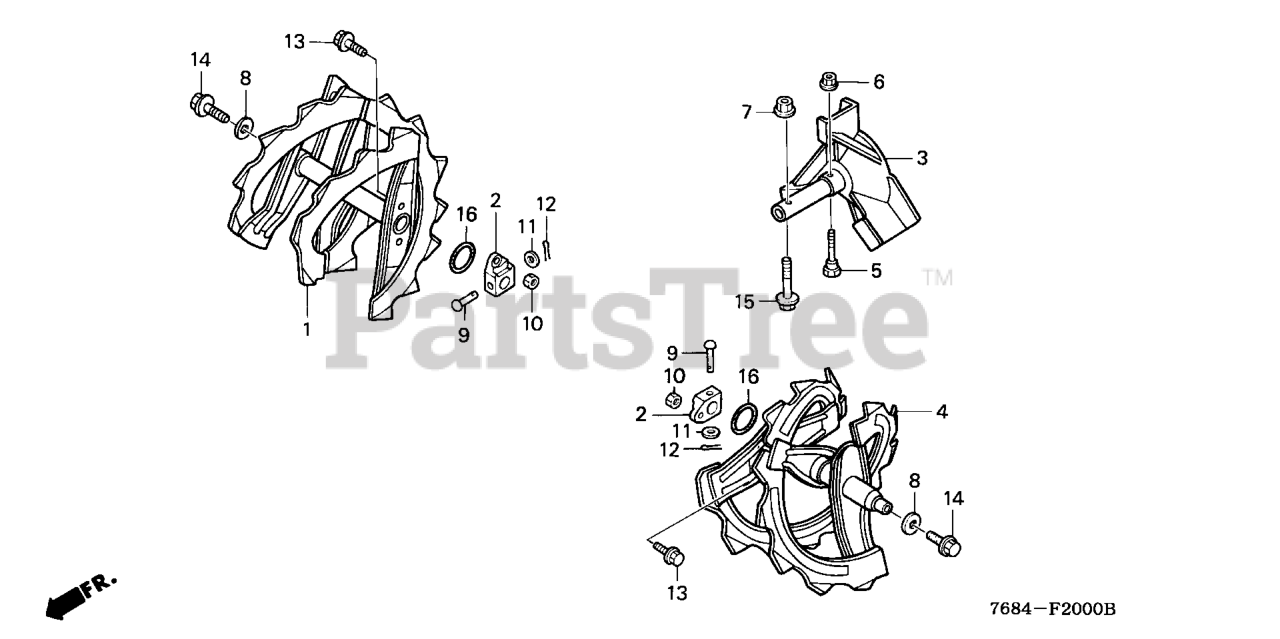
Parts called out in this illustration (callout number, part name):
2	BOSS, LOCK BOLT
5	BOLT, LOCK
6	NUT, SELF-LOCK (6MM)
7	NUT, FLANGE (8MM)
8	WASHER (8MM)
9	PIN (7X40)
10	NUT, HEX. (6MM)
11	WASHER, PLAIN (7MM)
12	PIN, SPLIT (3.0X25)
12	PIN, COTTER (3.0X45)
13	BOLT, FLANGE (6X16) Use from Engine SN 2056820.
14	BOLT, FLANGE (8X16) Use from Engine SN 1000016.
15	BOLT, FLANGE (8X35)
NI	AUGER SKID KIT, COMMERCIAL
